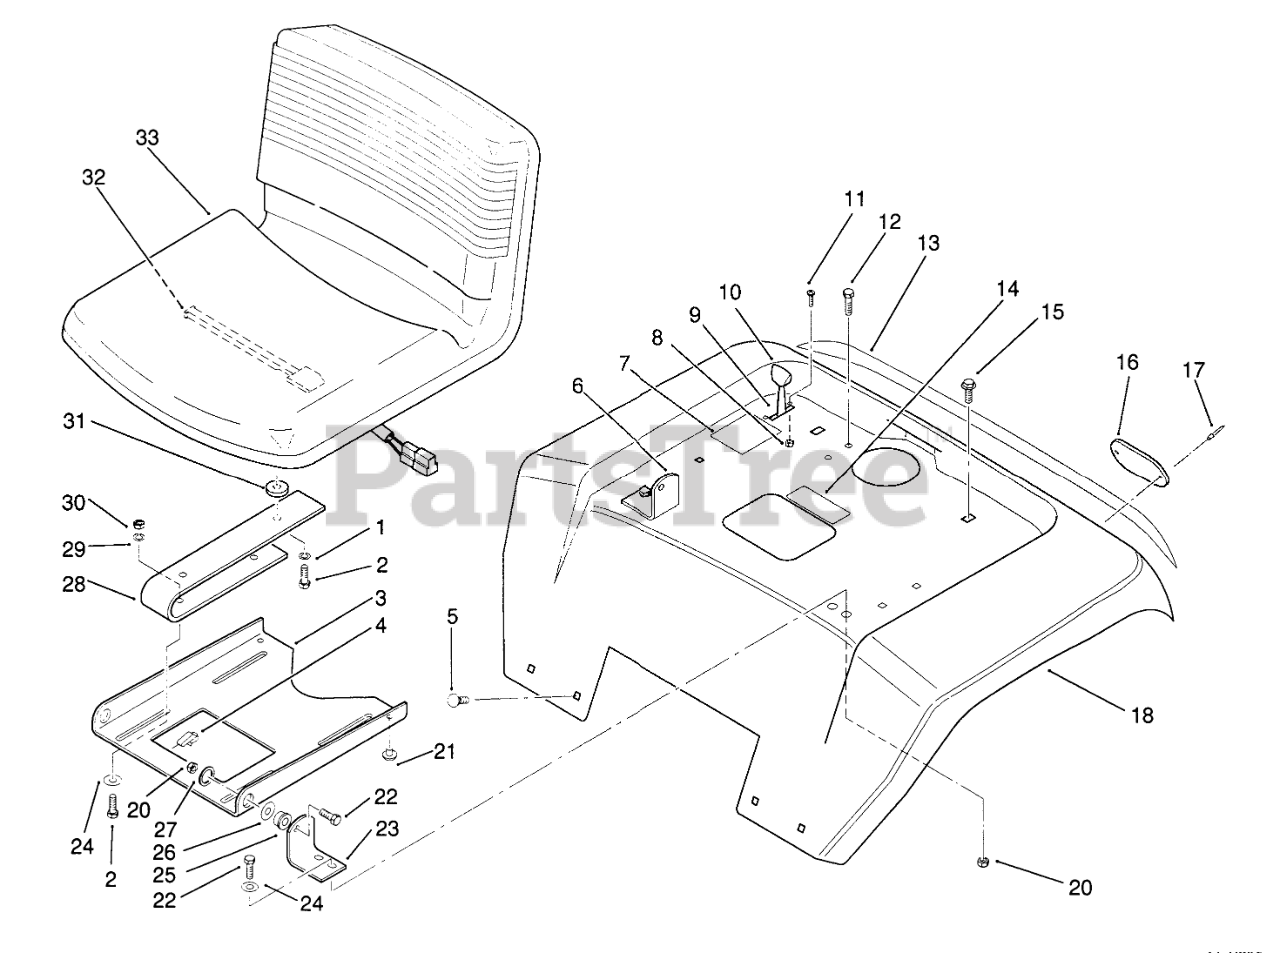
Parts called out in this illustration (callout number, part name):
1	Lockwasher
2	HHCS
3	Plate-SeatPivot
4	J-CLIP
5	Bolt-Carriage
6	Bracket-Pivot RH
7	DECAL-PUSH
8	Nut
9	CONTROL-PUSH VALVE
10	KNOB-THROTTLE
11	SCREW
12	Screw-Hex Hd.
13	DECAL-FENDER
14	DECAL-DANGER
15	Screw
16	Reflector
17	Poprivet
18	WLDMT-FENDER R
21	BUMPER-RUBBER
22	Screw-Cap Hex. Hd.
23	BRKT-PIVOT L.H. B
24	WASHER 5/16 SAE
25	BUSHING
26	WASHER-SPECIAL
27	WASHER-SPRING
28	Seat Spring
29	LOCKWASHER
30	Nut
31	SPACER-NYLON
32	SWITCH-SEAT
33	SEAT V-410
